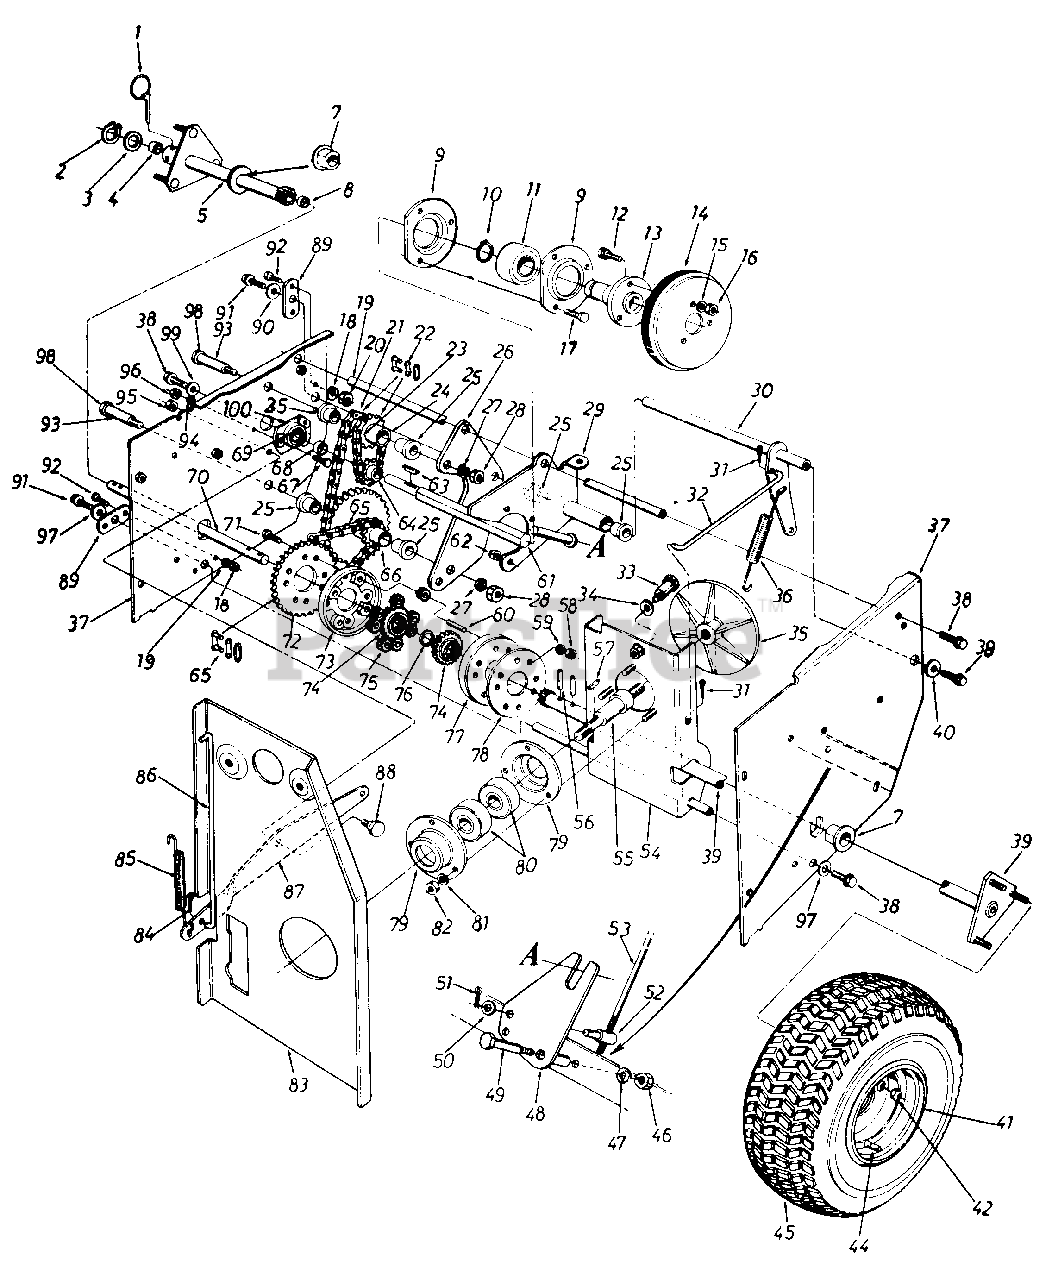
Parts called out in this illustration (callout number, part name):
1	Klick Pin 1/4" Dia. x 1.75"
2	Snap Ring .625" Shaft
3	Fl-Wash. .62" I.D. x 1.25"
4	Sleeve Brg.
5	Differential Tubing Ass'y. R.H.
7	Flange Brg. w/Flats 1" I.D.
8	Sleeve Brg.
9	Bearing Housing
10	Snap Ring 1.00" Dia.
11	Ball Brg .25MM x 52MM x 15MM Thk.
12	Hex Sems Bolt 5/16-18 x .75" Lg.
13	Friction Wheel Adapter
14	Friction Wheel Ass'y.
15	L-Wash. 5/16" I.D.
16	Hex Nut 5/16-18 Thd.
17	Hex Bolt 1/4-28 x .62" Lg.
18	L-Wash. 1/4" I.D.
19	Sliding Support Axle
20	Hex Nut 1/4-20 Thd.
21	#41 Chain 1/2" Pitch x 43 Links
22	Master Link
23	#41 Chain 1/2" Pitch x 19 Links
24	9 and 14 Teeth Sprocket Hub Ass'y.
25	Flange Brg. .630" I.D.
28	Hex L-Jam Nut 3/8-24 Thd.
29	Sliding Brkt. Ass'y.
30	Drive Clutch Brkt. Ass'y.
31	Inter. Cot. Pin 5/16" Dia.
32	Drive Clutch Rod 7.38" Lg.
33	Shld. Bolt
34	Bell-Wash. .44" I.D. x .88"
35	Aluminum Drive Plate
36	Extension Spring 4.31" Lg.
37	Frame Ass'y.
38	Hex L-Bolt 5/16-18 x .62"
39	Differential Shaft Ass'y.
40	Fl-Wash. .345" I.D. x .75"
41	Rim Only 16"
42	Cone Nut 3/8-24 Thd.
44	Tubeless Air Valve
45	Wheel Ass'y. Comp. 16 x 6.5
46	Hex Jam Nut 3/8-16 Thd.
47	L-Wash. 3/8" I.D.
50	Fl-Wash. .344" I.D. x .62"
51	Cotter Pin 3/32" Dia. x .75"
52	Adjustment Ferrule
53	Shifting Rod
56	H-Spring Pin Spiral 3/16" Dia. x 1.25" Lg.
57	#61 Hi-Pro Key 3/16 x 5/8" Dia.
58	Hex Nut 1/4-28 Thd.
59	L-Wash. 1/4 I.D.
60	Differential Pin
61	Hex Shaft
62	Hex L-Nut l/4-28 Thd.
63	#9 Hi-Pro Key 3/32 x 5/8" Dia.
64	8 Teeth Sprocket
65	#420 Chain .50 Pitch x 37 Links
66	9 and 32 Teeth Sprocket Hub Ass'y.
67	Hex Bolt 1/4-20 x .62" Lg.
68	Spacer .51" I.D. x .69" O.D.
69	Ball Bearing
70	Differential Connecting Shaft
71	Hex Bolt 1/4-28 x 1.75" Lg.
72	28 Teeth Sprocket
73	Differential Housing
74	20 Tooth Spur Gear
75	9 Tooth Spur Gear
76	Fl-Wash. .62" I.D. x 1.25"
77	Differential Housing
78	Differential Hsg. Support Plate
79	Bearing Housing
80	Ball Brg. .787" I.D. x 1.85"
81	L-Wash. 5/16" I.D.
82	Hex Nut 5/16-18 Thd.
83	Engine Brkt. Ass'y.
84	Inter. Cotter Pin 5/16" Dia.
85	Extension Spring 3.18" Lg.
86	Auger Clutch Rod .31" Dia. x 10.62" Lg.
87	Auger Clutch Brkt.
88	Shld. Bolt .625" Dia. x .170
89	Pivot Axle Brkt.
90	Fl-Wash. .345" I.D. x .75"
91	Hex L-Bolt 5/16-18 x .62"
92	Hex Bolt 1/4-20 x .62" Lg.
93	Sprocket Hub Tubing 1.88"
94	L-Wash. 1/4" I.D.
95	Hex Cent. L-Nut 3/8-16 Thd.
96	Hex Nut 1/4-20 Thd.
97	Fl-Wash. .344" I.D. x .375"
98	Hex Bolt 3/8-24 x 2.75" Lg.
99	Bell-Wash. .345" I.D. x .88"
100	Bearing Housing
